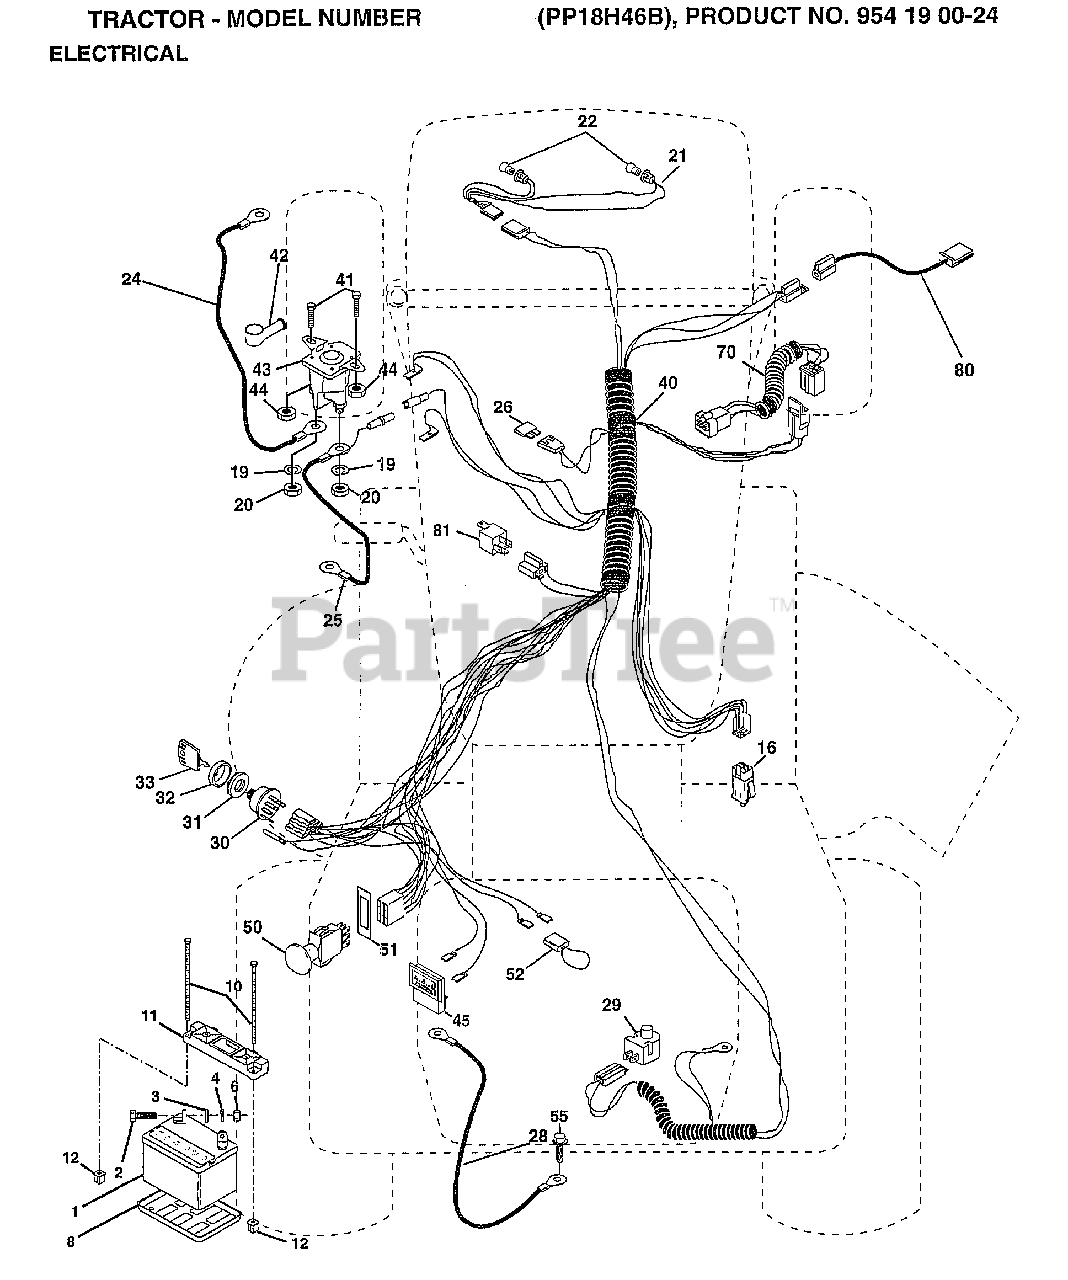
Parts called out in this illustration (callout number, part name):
2	BOLT LT
3	WASHER
4	LOCKWASHER
8	"TRAY T, BATTERY"
11	HOLDDOWN BATTERY
16	SWITCH INTERLOCK
20	NUT
21	"HARNESS,LIGHT SOC"
22	HEADLAMP BULB
24	"CABLE T, BATTERY"
25	CABLE.6GA.22W/16W
26	FUSE HYT
28	CABLE.GRND.6GA.21
29	SWITCH.PLUNGER
30	SWITCH IGN 4POS
31	NUT IGNITION
32	COVER KEY SWITCH
33	KEY
40	IGNITION HARNESS
41	BOLT HXHD FIN
44	NUT HXKEP 1/4X20
45	AMMETER
50	PTO SWITCH.BLK
51	RING RETAIN PTO
52	PROTECTION LOOP
55	SCREW LT
70	HARNESS.ENG.
80	HARNESS.CLUT.EVX.
81	RELAY ASSY T
